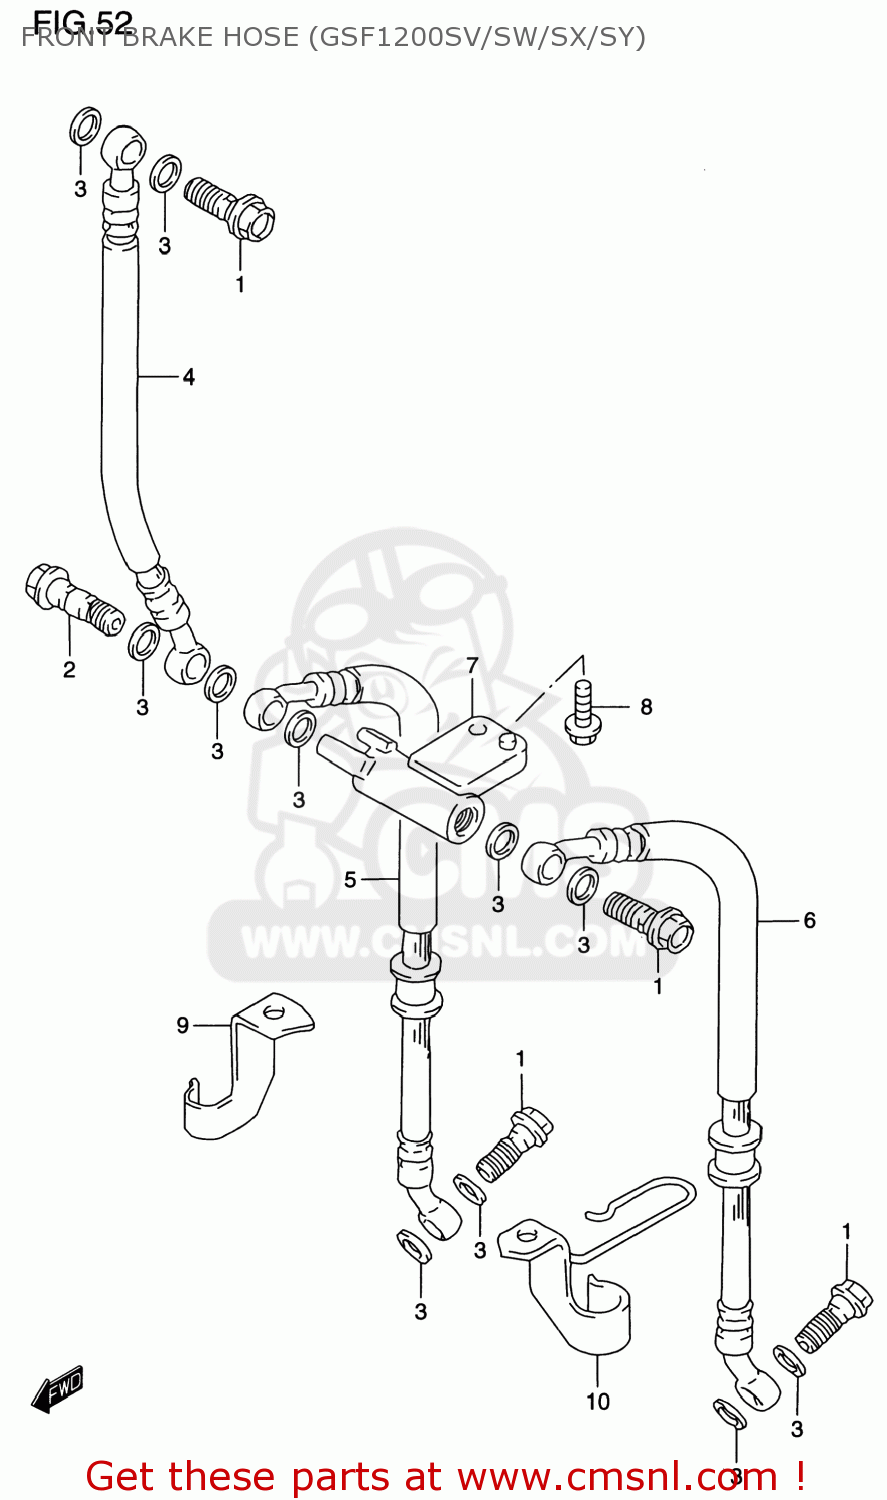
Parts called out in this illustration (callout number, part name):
1	BOLT UNION
2	BOLT UNION
3	WASHER(10X15X1.5)
4	HOSE COMP,FRONT BRAKE
5	HOSE,FR BRAKE NO.2,R
6	HOSE COMP,FRONT BRAKE
7	JOINT,BRAKE HOSE
8	BOLT
9	CLAMP,FR BRAKE HOSE,R
10	CLAMP,FR BRAKE HOSE,L
